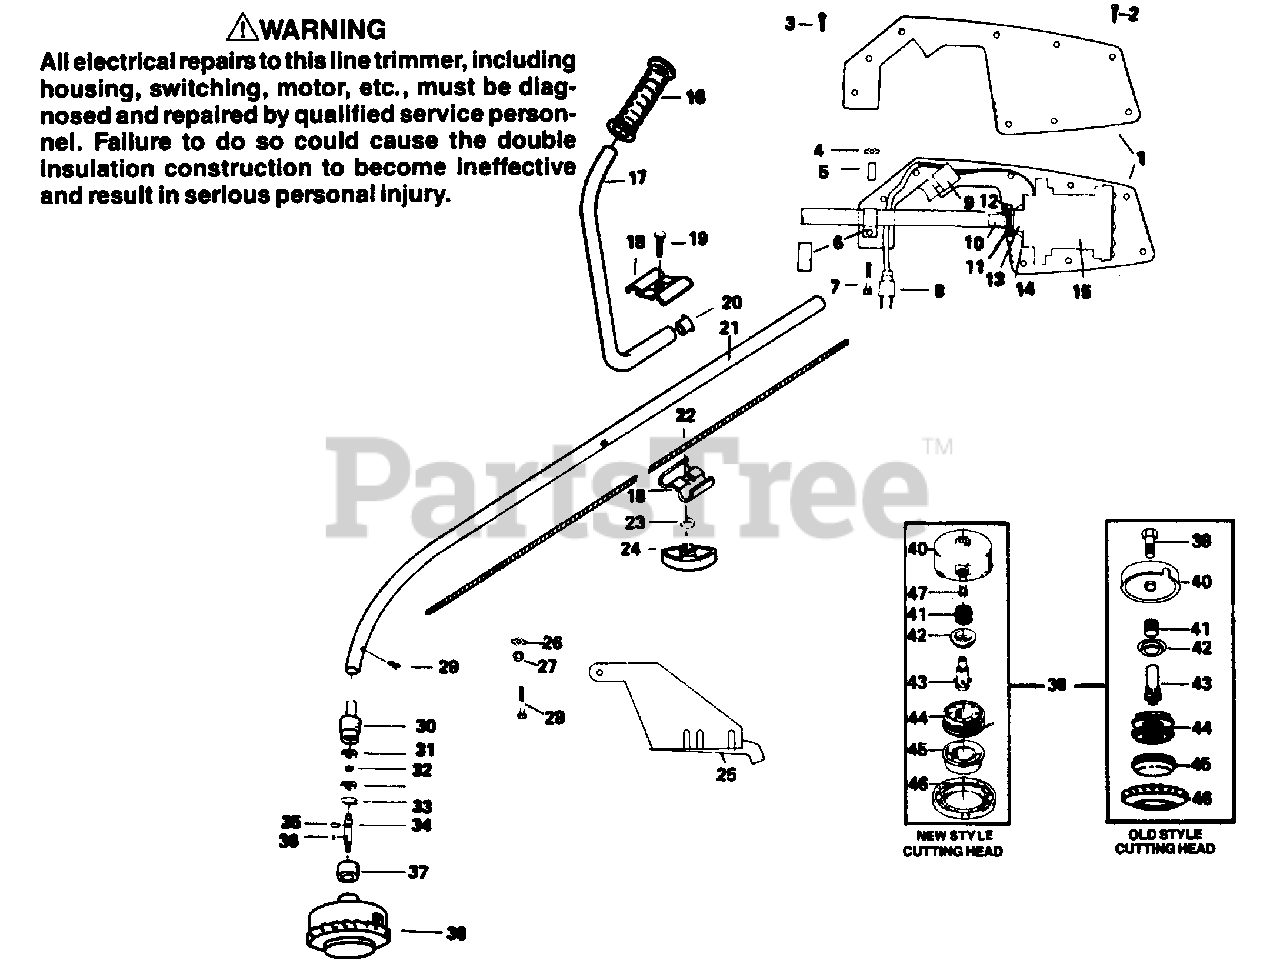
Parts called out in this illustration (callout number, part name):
1	Motor Housing Set
4	Wing Nut
5	Tube Clamp Bushing
8	Power Cord
10	Drive Coupling
13	Lube Connector
15	Motor Assembly
17	Handle Bar
20	Handle Bar Plug
21	Drive Shaft Housing
22	Drive Shaft
26	Wing Nut
27	Flat Washer
30	Bearing Housing
33	Retaining Ring
34	Arbor Shaft
35	Retaining Ring
36	Woodruff Key
37	Dust Cover
38	Cutting Head Assembly New Style
38	Cutting Head Assembly Old Style
39	Bolt - Drive Adaptor - Old Style
40	Hub w/Line Savers - Old Style
40	Hub w/Line Savers - New Style
41	Coil Spring
42	Coil Spring Adaptor
43	Drive Gear Old Style
43	Drive Gear New Style
44	Spool, Wound
45	Release Button
47	Line Saver - New Style only
